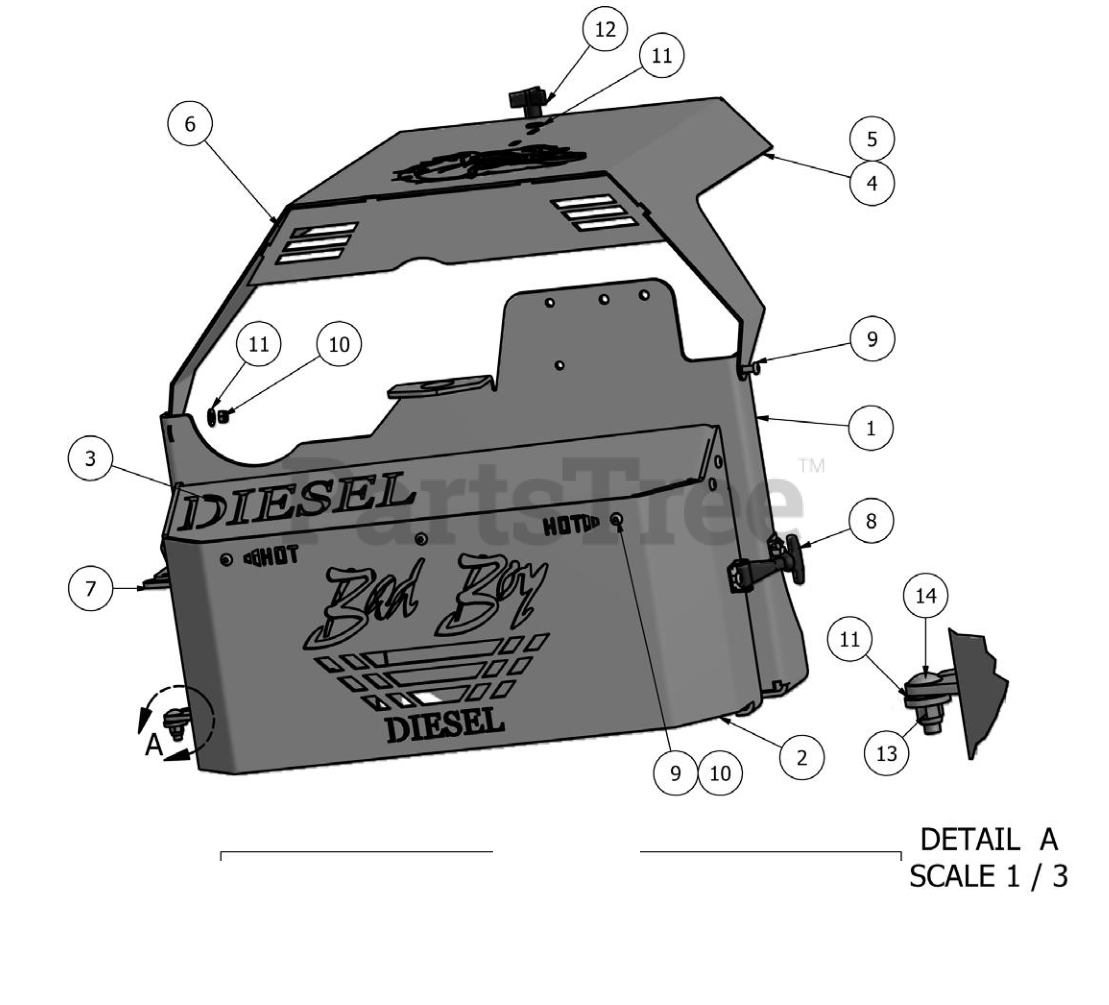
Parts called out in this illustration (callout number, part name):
1	Pump Plate
2	Back Pump Cover
3	Top Back Cover
4	35 HP Hood
5	28 HP Hood
6	Back Cover For Hood
7	Pump Cover Hinge
8	Pump Cover Latch
9	5/16" x 3/4" Bolt
10	5/16" Nylock Nut
11	.360 ID Plastic Washer
12	5/16" Knob
13	5/16" Nylock Nut
14	5/16" x 3/4" Carraige Bolt
